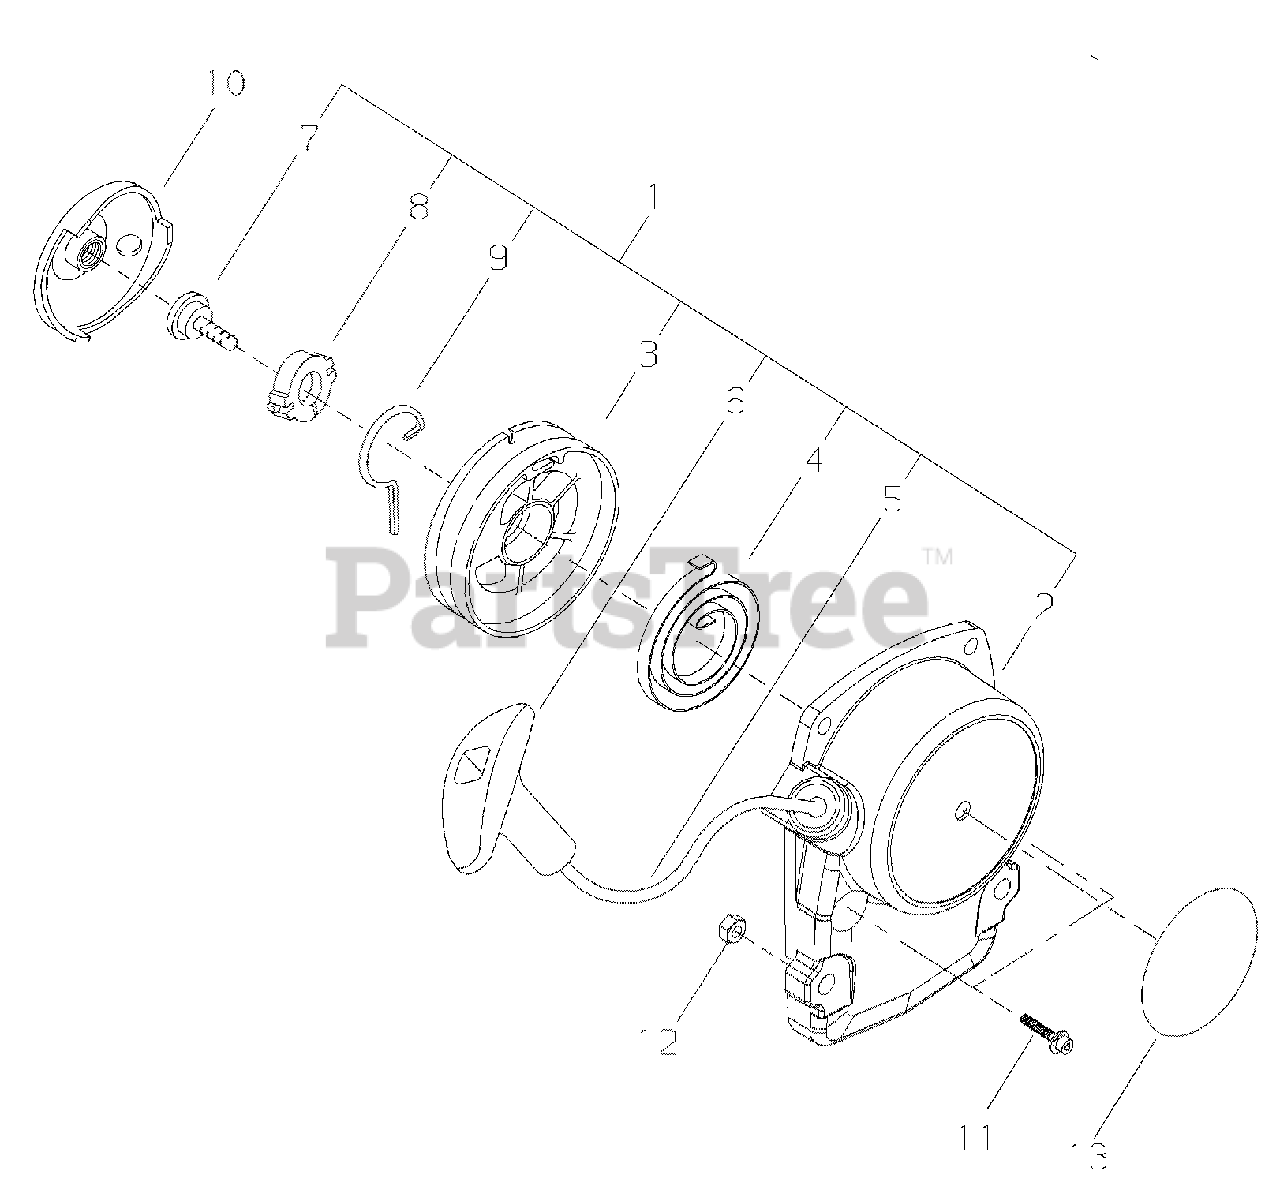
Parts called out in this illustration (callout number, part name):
1	STARTER ASSY, RECOIL
2	CASE, RECOIL STARTER
3	REEL, ROPE
4	SPRING, RECOIL
5	ROPE, STARTER
6	GRIP, STARTER
7	SCREW 5
8	WASHER 5
9	ARM, SWING
10	PULLEY, STARTER
11	BOLT M4×16
12	NUT M5
13	LABEL, C242
